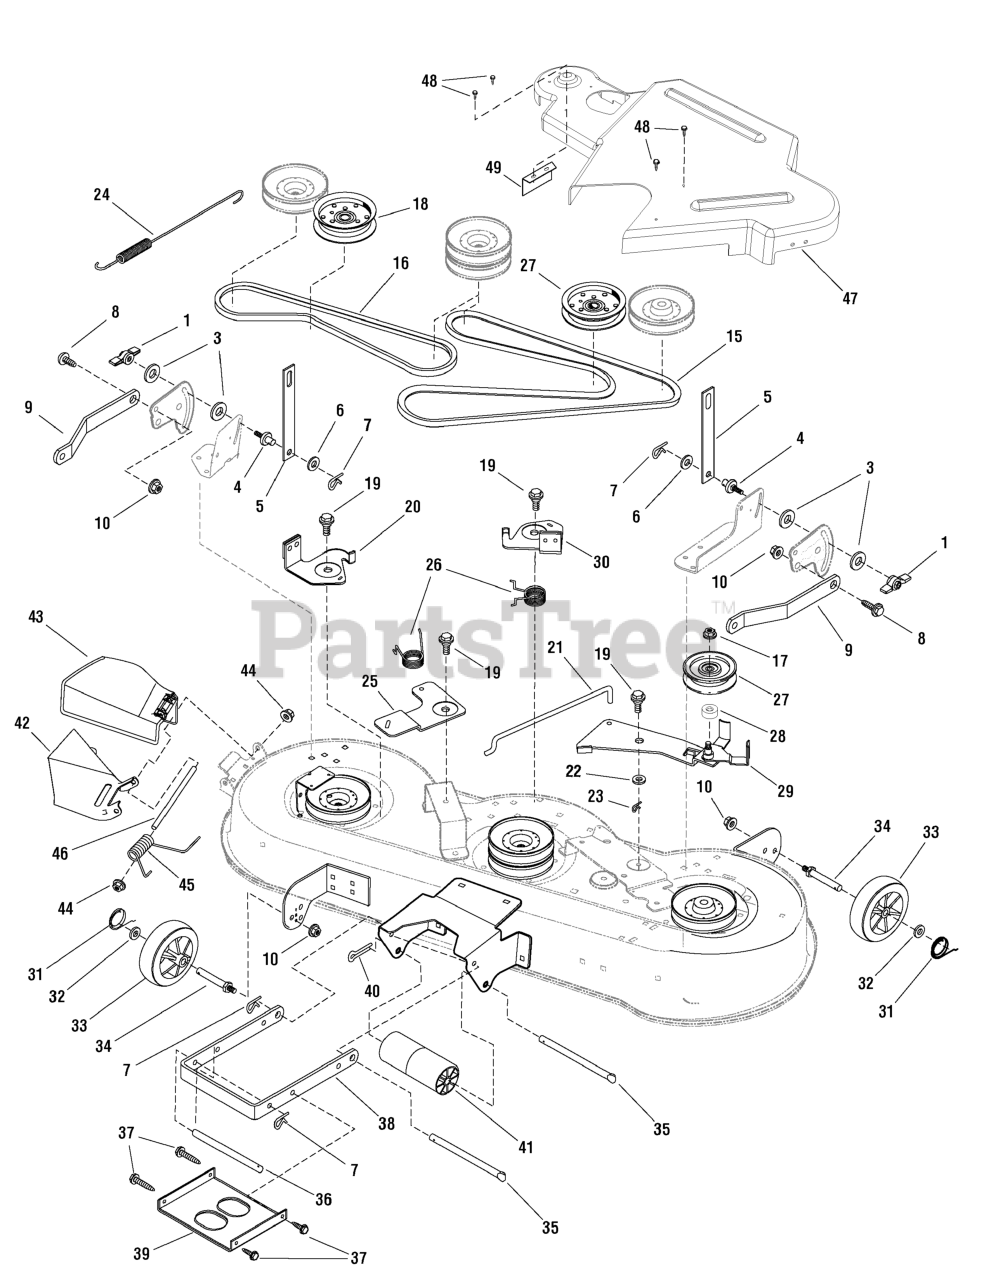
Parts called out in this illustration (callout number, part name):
1	KNOB, (5/16-18 thread)
3	FRICTION PAD
4	PIN, Hanger 3/8-16 x 1-1/4
5	LINK, Lift
6	WASHER, Flat 1
7	PIN, Hair
8	BOLT, Shoulder 3/8-16 x 1
9	BRACKET, Rear Suspension
10	NUT, Hex Flange, 3/8-16
15	BELT, Primary 46 in
16	BELT, Secondary, 46 in
17	NUT, Flange, 3/8-16
18	PULLEY, Idler, Right
19	BOLT Shoulder 3/8-16 x 3/4
20	BRAKE ASSEMBLY, Center
21	LINK, Bellcrank
22	Washer, Flat 5/8"
23	PIN, Cotter, 3/4
26	SPRING, Torsion Brake
27	PULLEY, Idler, Left
28	SPACER, 1/2" TO 17mm
29	IDLER ARM, 46 in, Left
30	BRAKE ASSEMBLY, Left
31	CLIP, Hair Pin
32	WASHER, Flat, 7/8
33	WHEEL GAGE
34	BOLT, Gauge Wheel
35	ROD, Deck Suspension
36	ROD, Hanger
37	CAPSCREW, 5/16-18
38	BRACKET, Front Suspension
40	COTTER PIN
42	DEFLECTOR, Inside
43	DEFLECTOR, Chute
44	CAP, Push On
45	SPRING, Torsion
46	ROD, Deflector
47	GUARD, 46"
48	SCREW, Hex, 1/4-20 x 1/2
49	PLATE, Guard, RH
